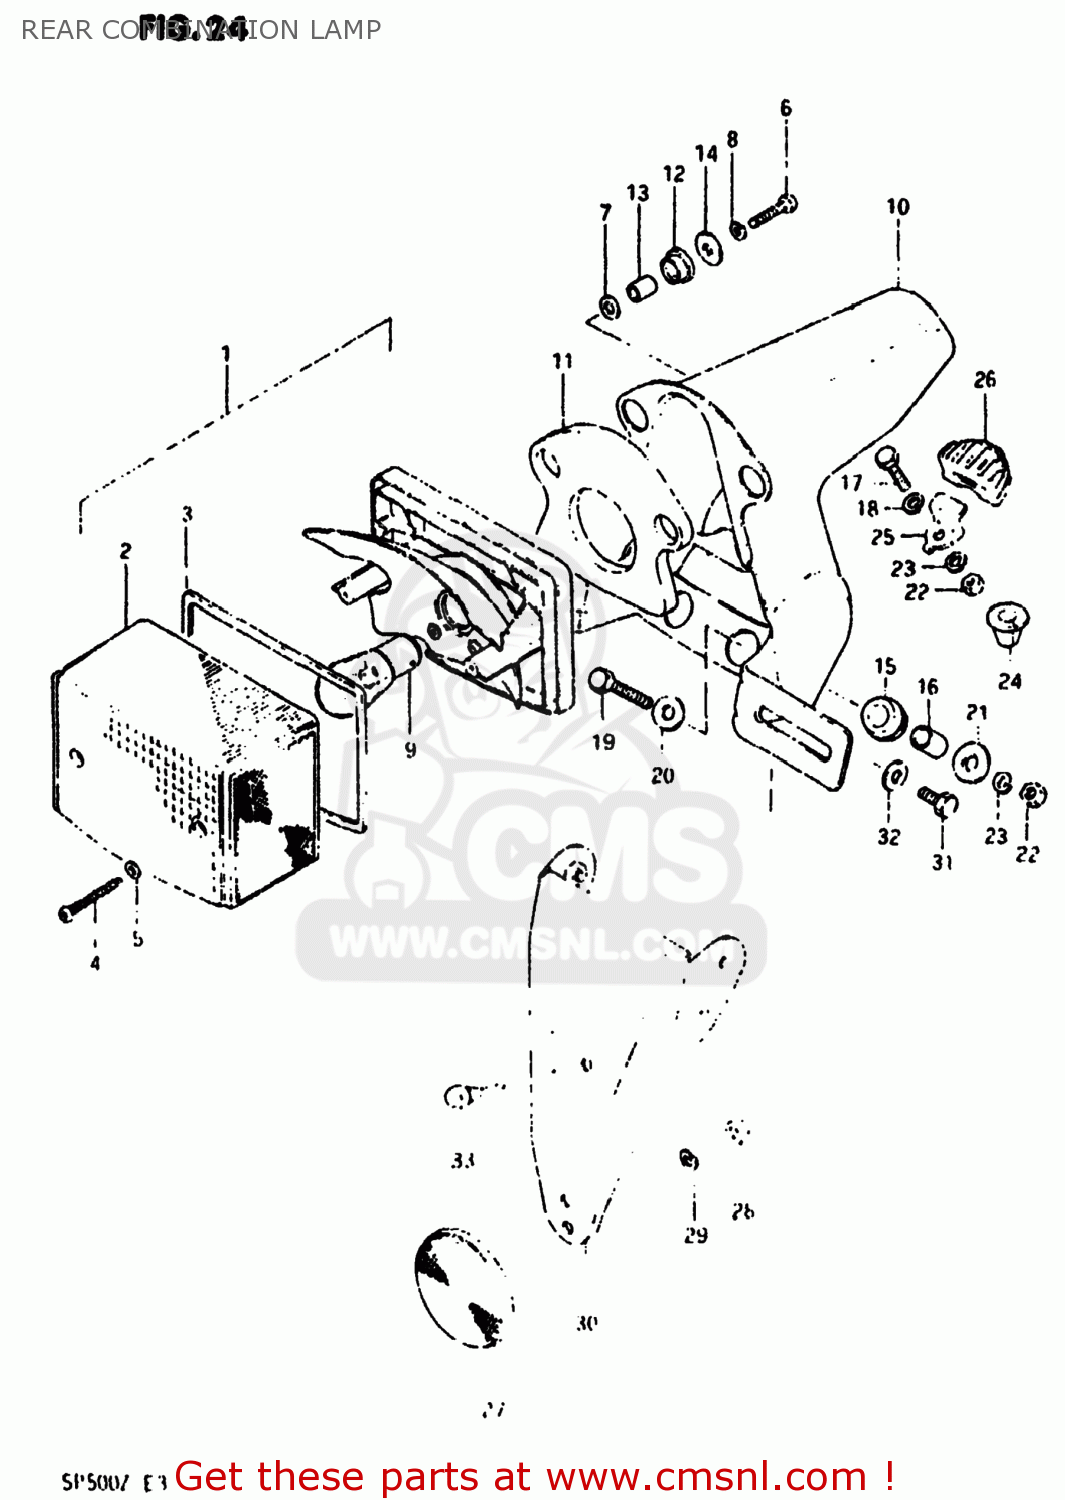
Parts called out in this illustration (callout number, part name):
1	LAMP UNIT,REAR COMBINATION
2	LENS
3	GASKET (NAS)
4	SCREW
5	GASKET (NAS)
6	SCREW
7	WASHER
8	LOCK WASHER
9	BULB(6V32/3CP,STANLEY)
10	BRACKET UNIT,TAIL LAMP
11	CUSHION,REAR COMBINATION LAMP
12	CUSHION,REAR COMBINATION LAMP
13	SPACER,REAR COMBINATION LAMP
14	WASHER,REAR COMBINATION LAMP
15	CUSHION,REAR COMBINATION LAMP
16	SPACER
17	BOLT
18	LOCK WASHER
19	BOLT
20	WASHER (6.5X20X1.2)
21	WASHER
22	NUT
23	WASHER
24	GROMMET
25	PLATE,TAIL LAMP
26	CUSHION,REAR COMBINATION LAMP
27	REFLEX REFLECTOR,RR
28	NUT
29	LOCK WASHER
30	BRACKET
31	BOLT
32	WASHER
33	CUSHION
